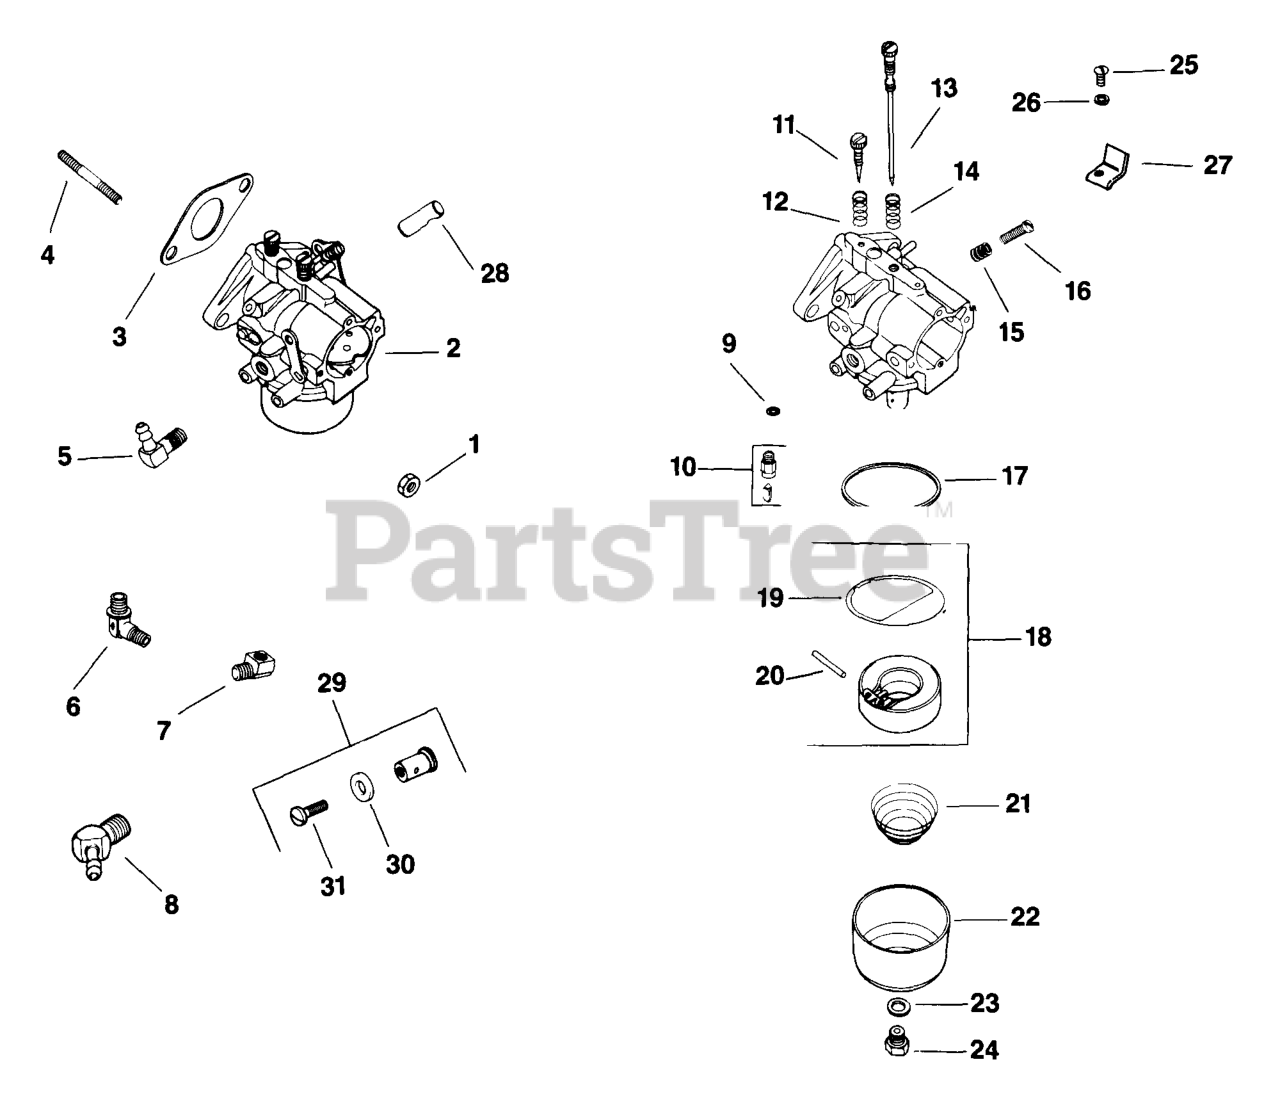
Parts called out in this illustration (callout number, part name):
1	NUT, 5/16-24 GRADE 2 USE 25 100 23-S
3	GASKET, CARBURETOR
4	STUD,5/16-24x1" USE 25 072 09-S
5	CONNECTOR, 90 DEG. HOSE
10	Needle and Seat
11	SCREW - DISCONTINUED
12	SPRING-(#DSC)
16	SPRING-(#DSC)
18	KIT, FLOAT REPAIR - DISCONTINUED
24	NUT - DISCONTINUED
28	BODY - DISCONTINUED
2575702-S	KIT, CARBURETOR REPAIR
